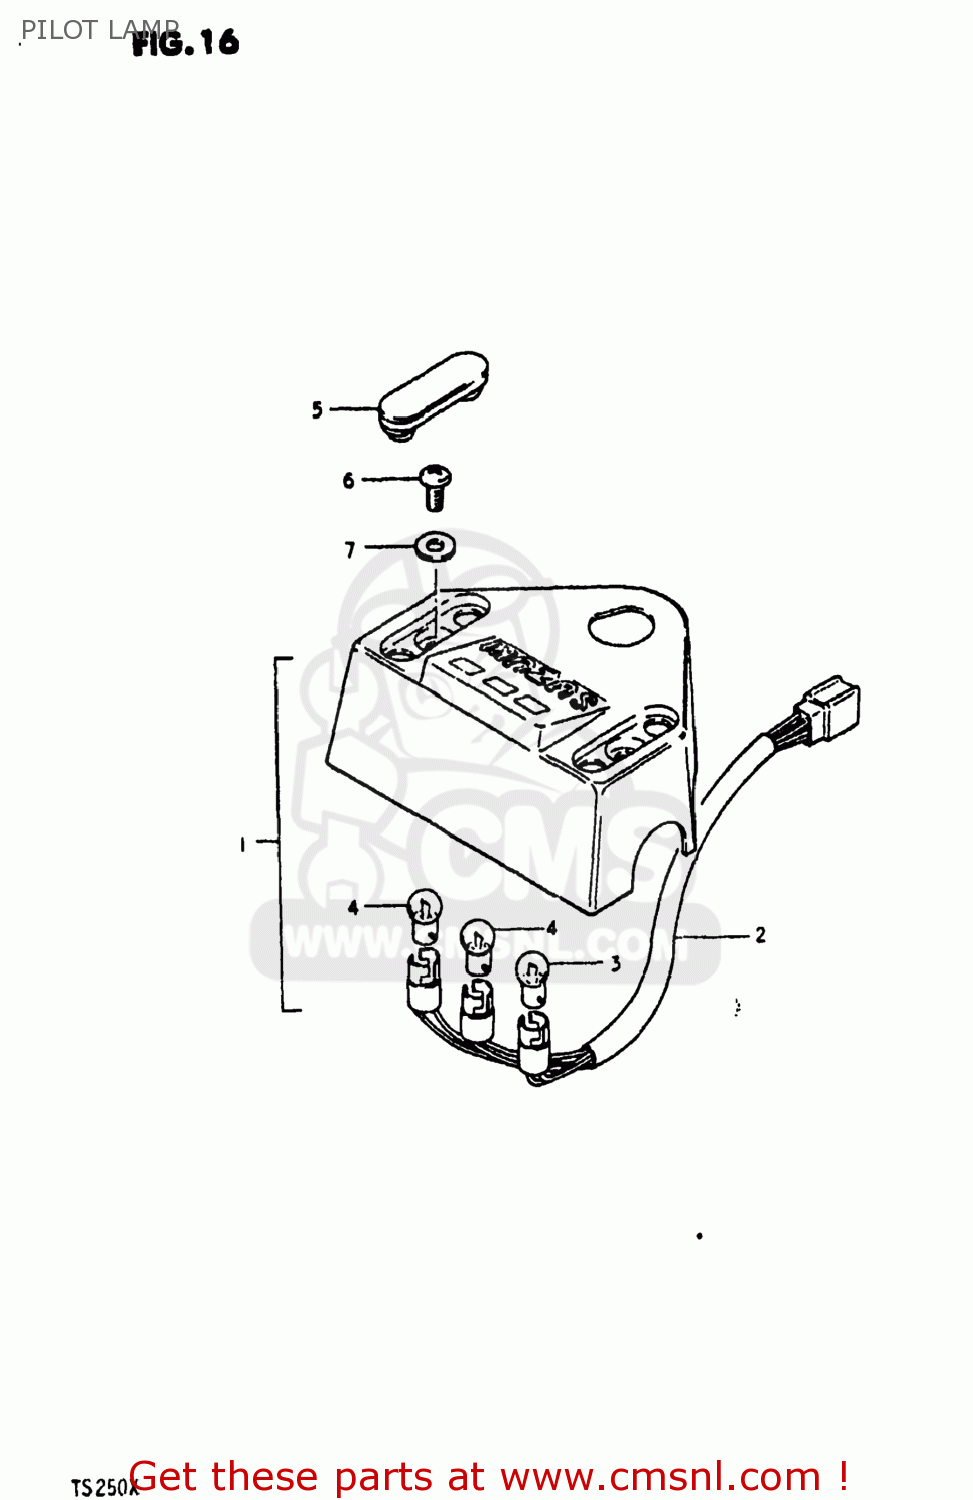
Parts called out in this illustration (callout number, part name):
1	CASE,PILOT BULB
2	SOCKET
3	BULB(6V1.7W,STANLEY,A61A)
4	BULB(6V/3W)
6	SCREW 6X12
7	WASHER
